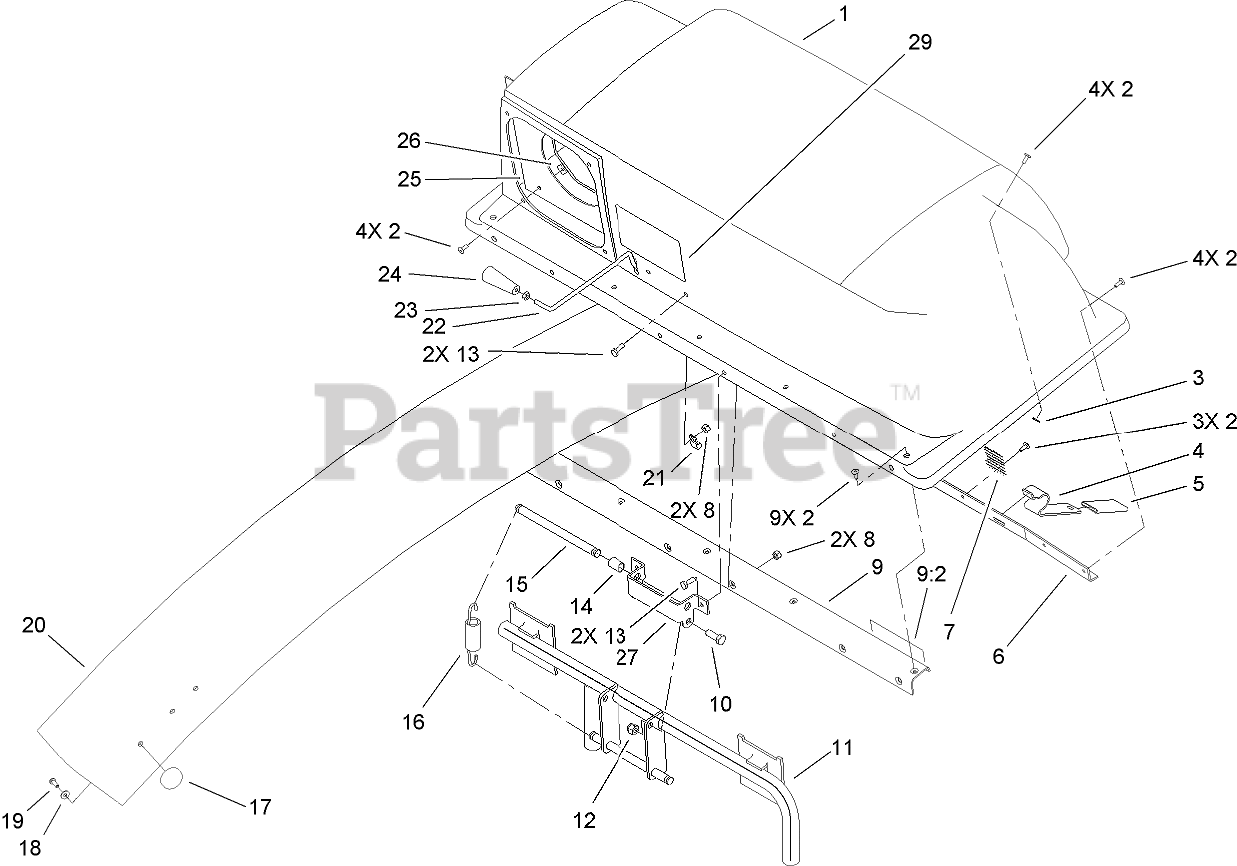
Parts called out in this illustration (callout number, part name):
1	TOP-BAGGER
2	RIVET-BLIND
3	WASHER-FLAT
4	LATCH-BAGGER, TOP
6	SUPPORT-SCREEN
7	SCREEN-BAGGER
8	NUT-LOCK, NI
9	STIFFENER ASM
9:2	DECAL-CAUTION
10	SCREW-HH
11	FRAME ASM
12	NUT-LOCK, NI
13	SCREW-HH
14	Spacer
15	PIN-SPRING
16	SPRING-EXTENSION
18	WASHER-PLAIN
19	SCREW-PPHTF
20	CHUTE-DISCHARGE
21	CLAMP
22	FEELER-FILL, BAG
23	NUT-JAM
24	HANDLE-TAPERED
25	SEAL-CHUTE
26	Hinge-Bag, Top
27	CLAMP-SEAL
29	DECAL
